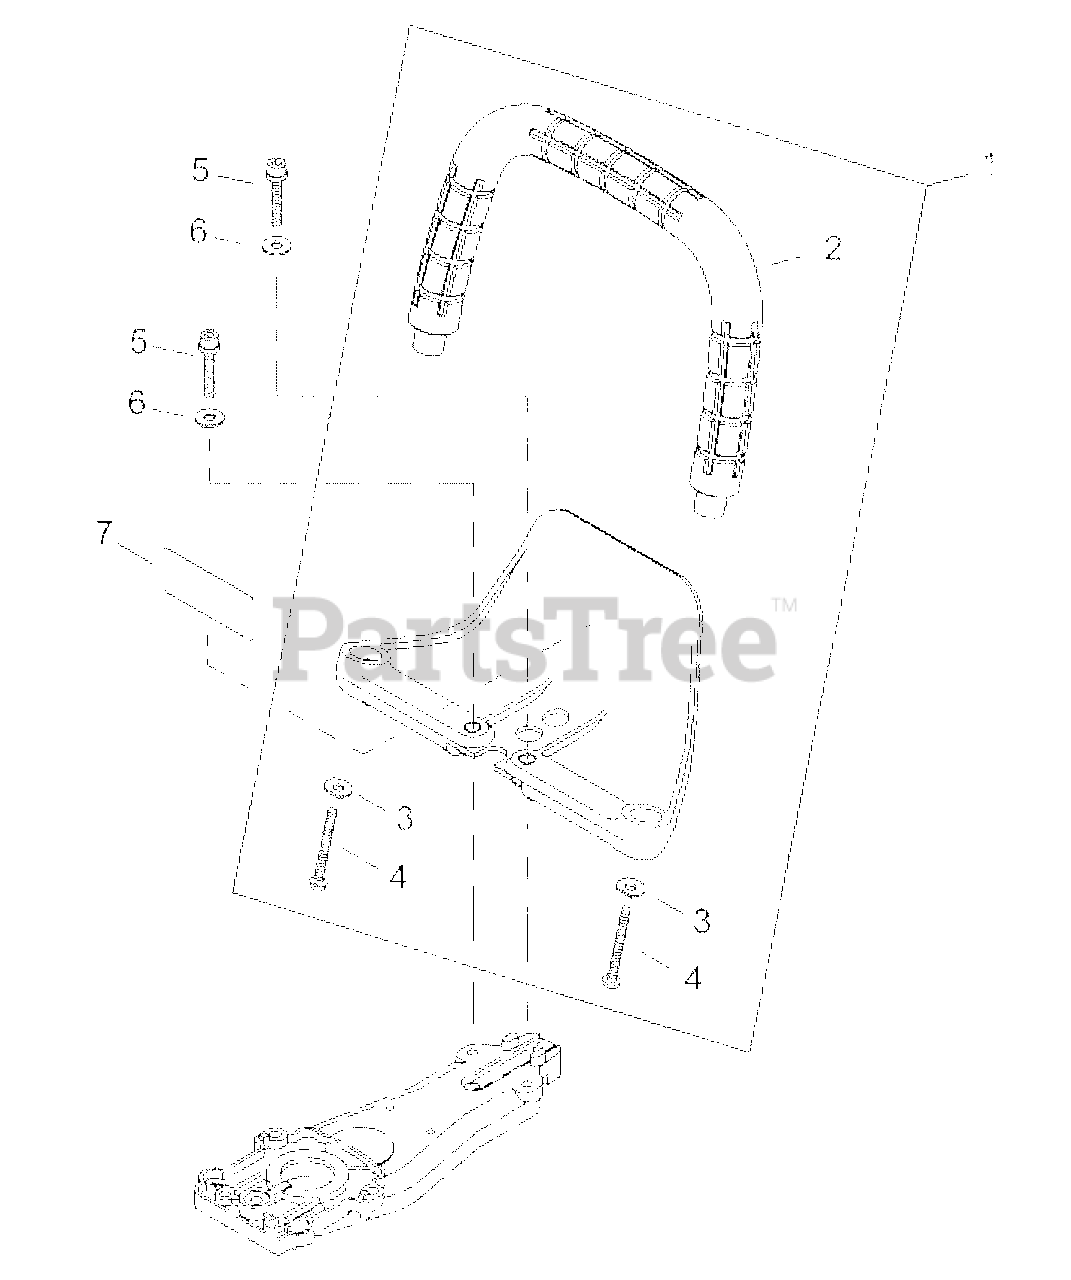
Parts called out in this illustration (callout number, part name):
1	HANDLE ASSY - FRONT
2	HANDLE - FRONT
3	WASHER
4	SCREW - 5 -- TAPPING
5	SCREW - 6X30
6	WASHER - 16
7	LABEL - CAUTION
